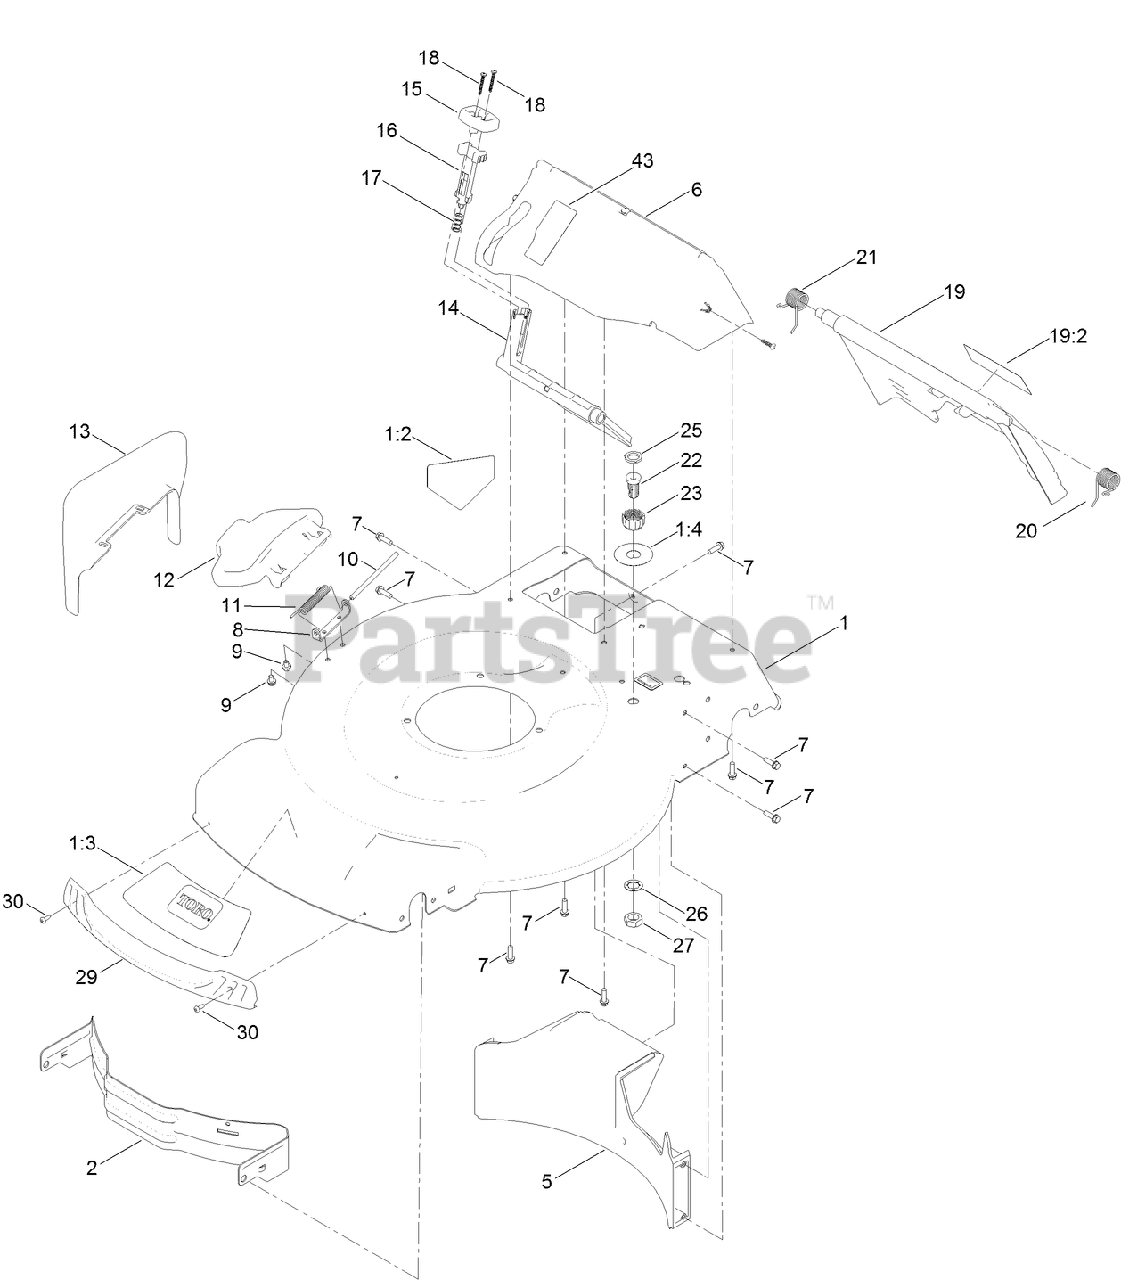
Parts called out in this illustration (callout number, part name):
1	HOUSING ASM
1:2	DECAL-DANGER
1:3	DECAL-RECYCLER
1:4	DECAL-PORT, WASHOUT
2	BAFFLE-FRONT
5	BAFFLE-REAR
6	CHUTE-RECYCLE
7	SCREW-HWH
8	BRACKET-COVER
9	SCREW-HWH
10	ROD-COVER
11	SPRING-TORSION
12	DEFLECTOR-SIDE
13	CHUTE-DISCHARGE, SIDE
14	DEFLECTOR-RECYCLE
15	KNOB-RECYCLE
16	LATCH-RECYCLE
17	SPRING-COMPRESSION
18	SCREW-PPH
19	REAR DOOR ASM
19:2	DECAL-WARNING
20	SPRING-TORSION
21	SPRING-TORSION
22	PORT-WASHOUT
23	COUPLING-HOSE, WASHOUT PORT
25	WASHER-SEAL, WASHOUT PORT
26	WASHER-TOOTH, INTERNAL
27	NUT-JAM
29	BUMPER
30	SCREW-FORMING, THREAD
